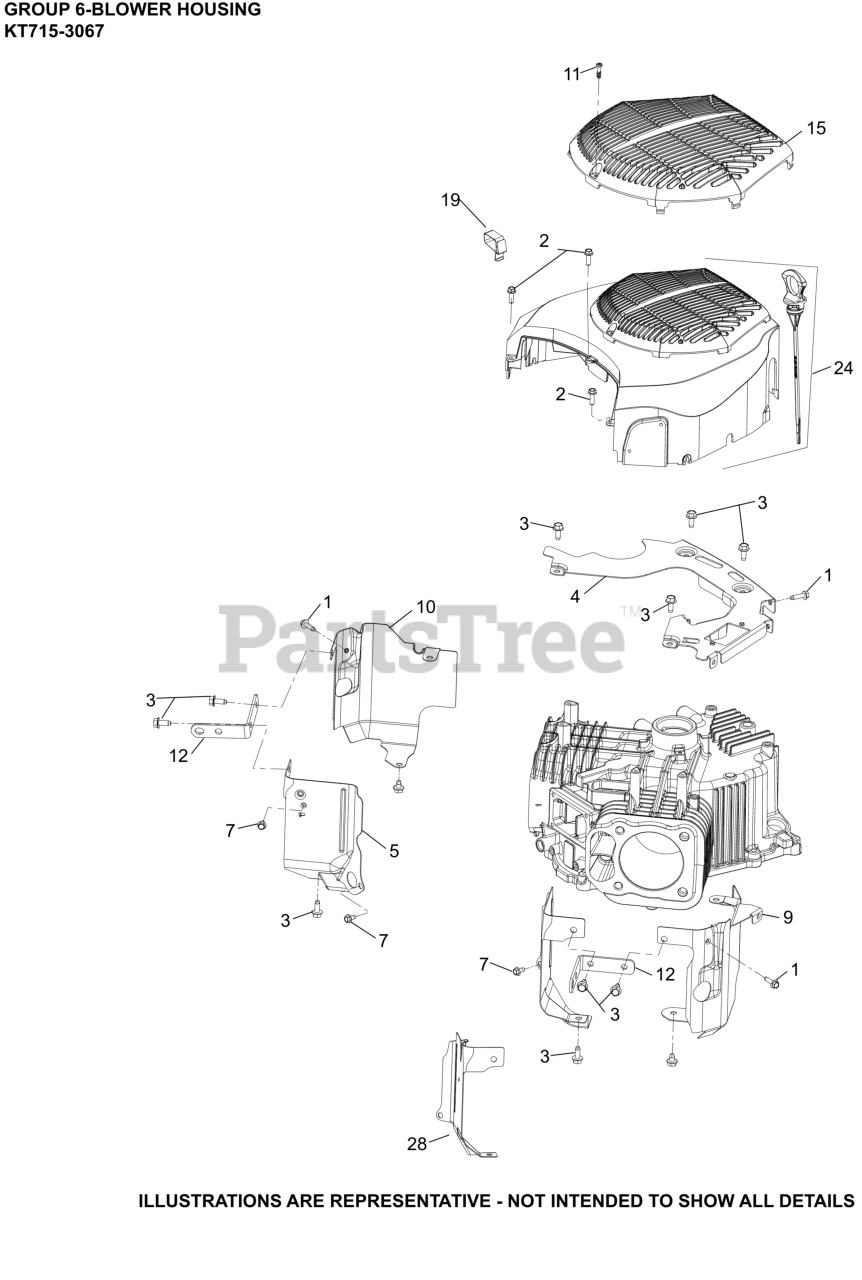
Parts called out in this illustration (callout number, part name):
1	SCREW, THD FRM-USE 25 086 473-S
2	SCREW, HI-LOW
3	SCREW, THREAD FORMING
4	PLATE, BACKING
5	BAFFLE, VALLEY #1
7	SCREW, THREAD FORMING
9	BAFFLE, LEFT BARREL
10	BAFFLE, RIGHT BARREL
11	SCREW, M5-2.42 (PT) THREAD
12	STRAP, LIFTING
15	GUARD, FIXED
19	CLIP, BLOWER HOUSING
24	KIT, BLOWER HOUSING
28	BAFFLE, VALLEY #2
